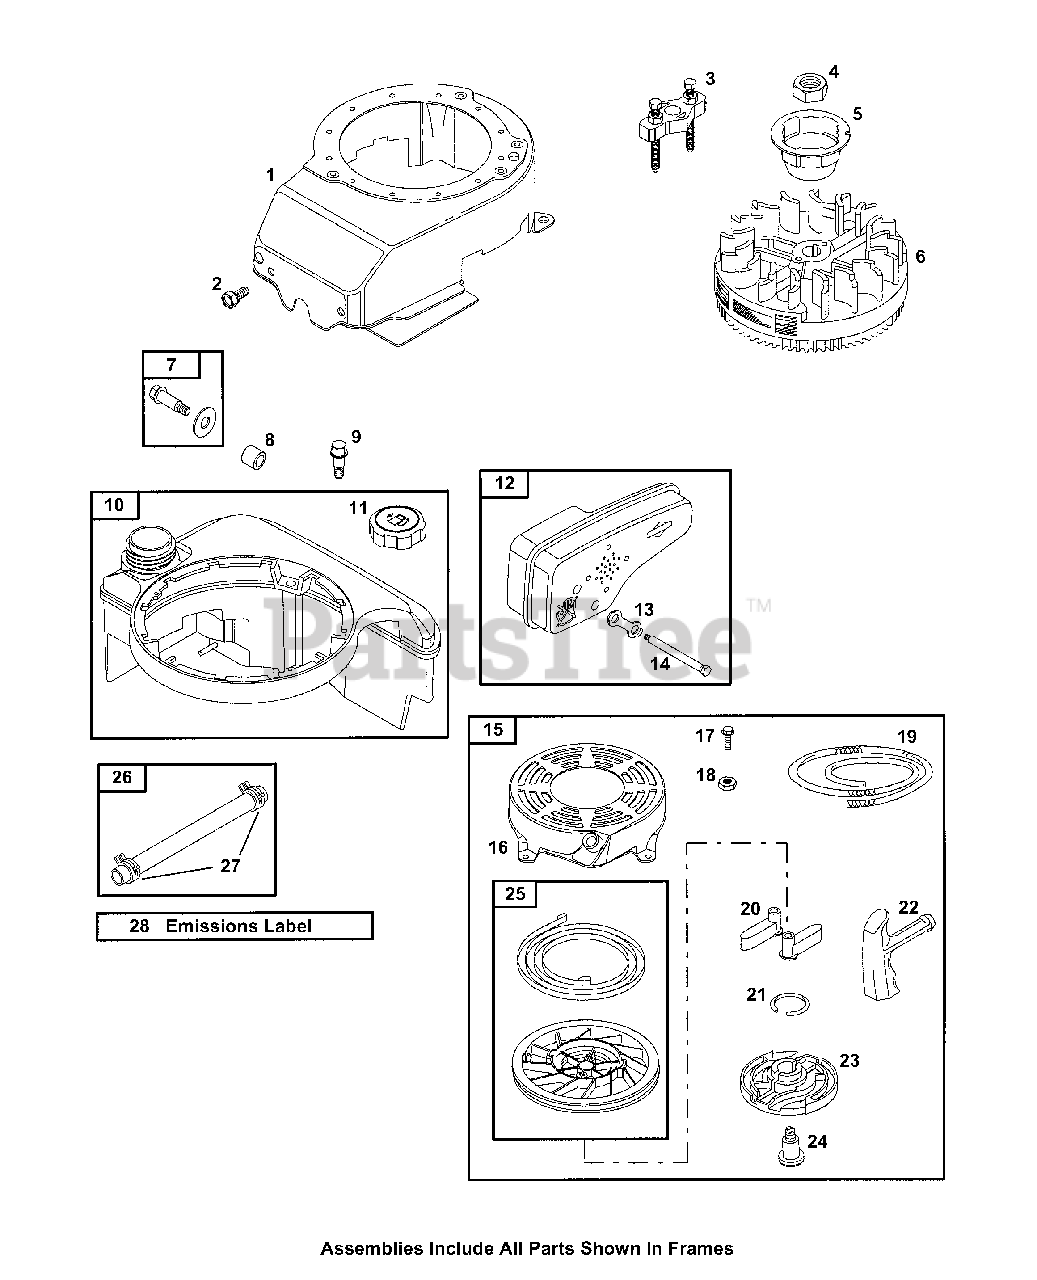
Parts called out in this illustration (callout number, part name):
1	Blower Housing
2	Screw (Blower Housing)
3	Flywheel Puller
4	Nut (Flywheel)
5	Flywheel Cup
6	Flywheel
7	Screw/Washer Kit
8	Fuel Tank Spacer
9	Screw (Fuel Tank)
10	Fuel Tank
11	Fuel Tank Cap
12	Exhaust Muffler
13	Muffler Screw Lock
14	Screw (Exhaust Muffler)
15	Rewind Starter
16	Rewind Starter Housing
17	Screw (Rewind Starter)
18	Nut (Rewind Starter Housing)
19	Starter Rope (Cut to Required Length)
20	Ratchet Pawl
21	Friction Spring
22	Starter Rope Grip
23	Pawl Friction Plate
24	Screw (Pawl Friction Plate)
25	Pulley/Spring Assembly
26	Fuel Line
27	Hose Clamp
28	Emissions Label
